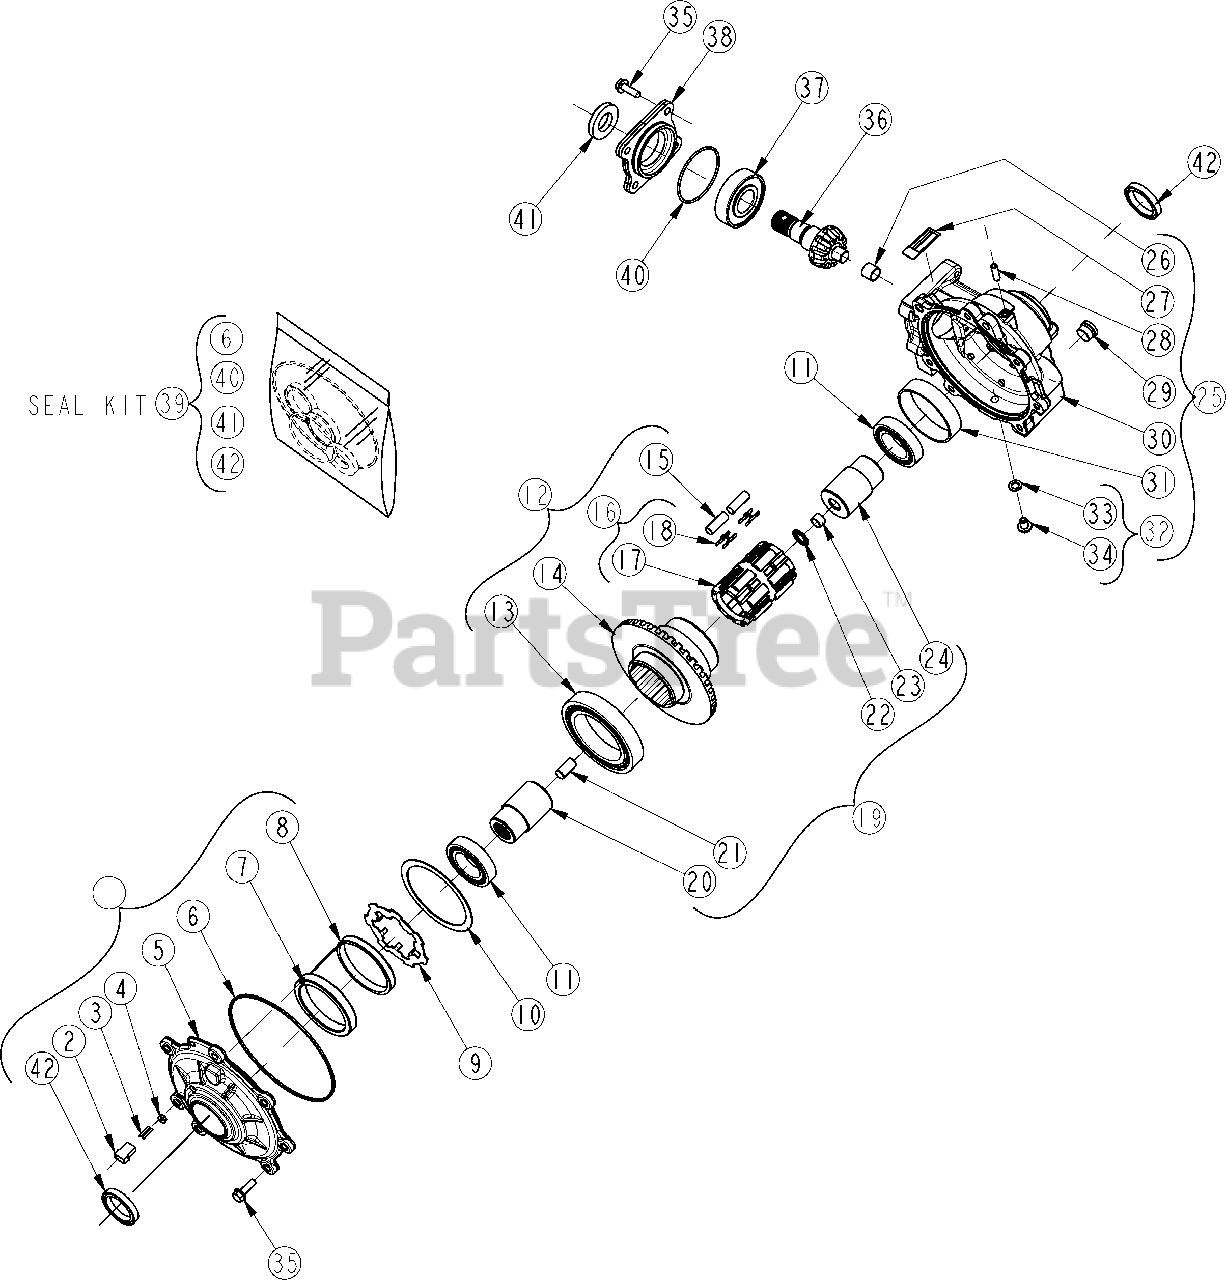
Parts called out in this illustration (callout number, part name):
1	OUTPUT COVER PLATE ASSEMBLY #1 Kit includes #2 to #8 & 42
9	ARMATURE PLATE
10	SHIM .05 THICK BRASS, HALF HARD
11	6008-C3 DEEP GROOVE ROLLER BEARING 4£
12	CLUTCH ASSEMBLY #12 Kit includes #13 to #16
13	6015-C3 DEEP GROVE ROLLER BALL BEARING Sold separately & with #12 kit
14	CLTH.HSG./RNG GR., 42T 6.75DP Sold separately & with #12 kit
15	ROLL KIT Sold separately & with #12 kit
16	ROLL CAGE ASSEMBLY #16 Kit includes #17 & #18
18	SPRING KIT, H-CLIP .008 THK Sold separately & with #16 kit
19	RACE/OUTPUT HUB ASSEMBLY #19 Kit includes #20 to #21
21	PERMIGLIDE BUSHING Sold with #19 kit
22	TC815 NEEDLE ROLLER THRUST BEARING Sold separately & with #19 kit
23	1/2 DIA X 1 LG. DOWEL PIN Sold separately & with #19 kit
25	GEARCASE ASSEMBLY #25 Kit includes #26 to #32
26	DU BUSHING Sold with #25 kit
29	PLUG OIL FILL 3/4-16 HOLLOW HEAD Sold separately & with #25 kit Torque item #29 (PLUG OIL FILL 3/4-16 HOLLOW HD) 10 ft*lbs.
32	DRAIN PLUG ASSEMBLY #32 Kit includes #33 & #34
35	BOLT KIT Torque item #35 (5/16" x 1" Hex Head Bolts) 17 ft*lbs
36	SHAFT PNION 11T3.75DP, MACHINED
37	6306-03-C3 DP GROOVE ROLLER BALL BEARING
38	COVER PLATE, INPUT-MACHINED
39	MINOR REPAIR KIT #39 Kit includes #6 & #40 to #42
41	TRIPLE LIP OIL SEAL Sold with #1 kit & #39 kit
42	OIL SEAL, OUTPUT Sold with #39 kit
